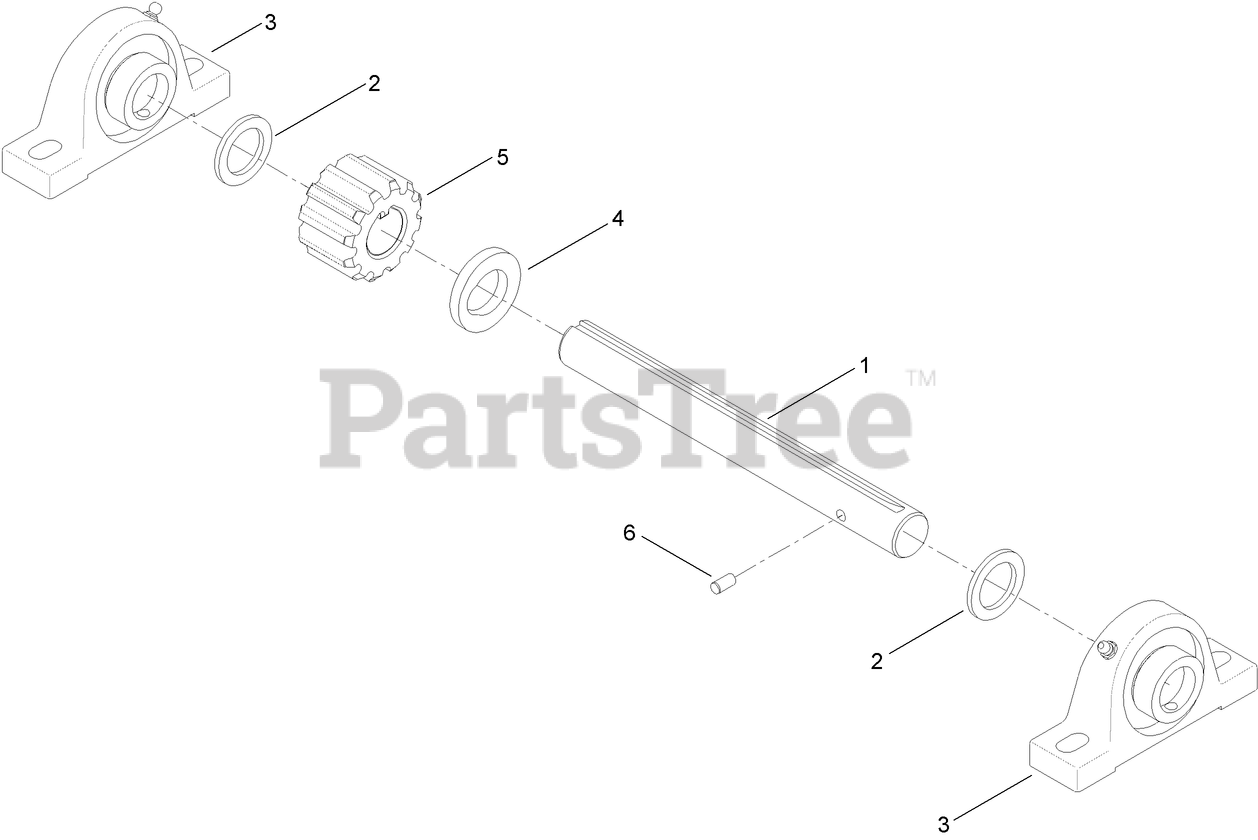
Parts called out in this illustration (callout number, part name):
1	SHAFT-PINION
2	WASHER-THRUST
3	BEARING-BLOCK, PILLOW
4	WASHER
5	GEAR-SPUR
6	PIN-DOWEL
